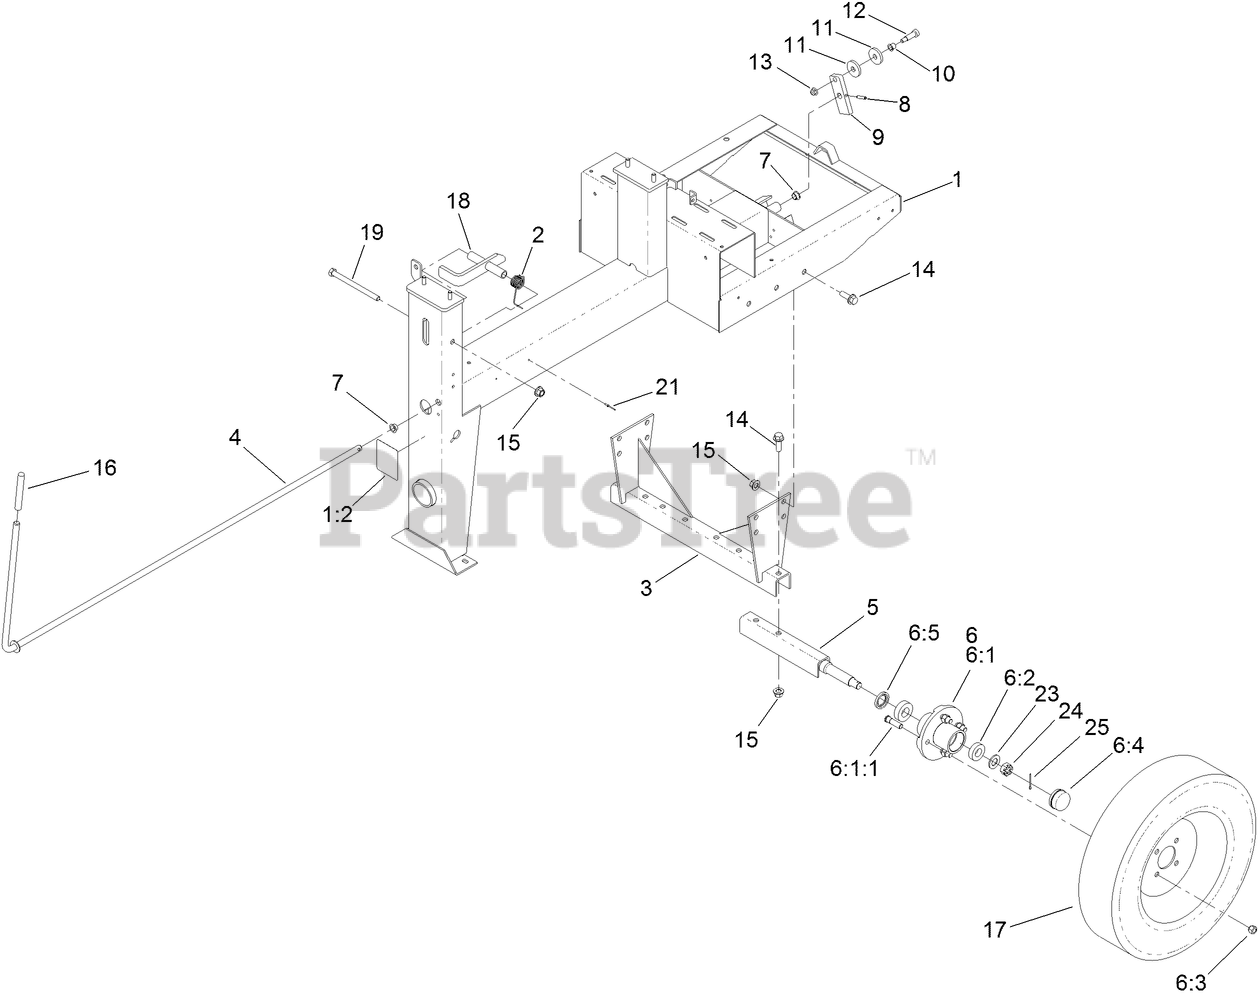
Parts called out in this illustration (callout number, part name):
1	FRAME ASM
1:2	DECAL-SAFETY CHAIN, TOWING
2	SPRING-TORSION
3	SUPPORT-AXLE
4	LEVER-CLUTCH
5	AXLE-HALF
6	HUB ASM
6:1	HUB-4IN
6:1:1	STUD-WHEEL
6:2	BEARING-ROLLER
6:3	NUT-LUG
6:4	CAP-DUST
6:5	SEAL-HUB, WHEEL
7	BUSHING-FLANGE
8	PIN-SPRING
9	LINK-CLUTCH
10	BUSHING-FLANGE
11	WASHER-FLAT
12	SCREW-HSBH
13	NUT-HF, NI
14	SCREW-HHF
15	NUT-LOCK
16	GRIP-HANDLE
17	TIRE AND RIM ASM
18	LATCH-DRUM
19	SCREW-HH
21	RIVET
23	WASHER-FLAT
25	PIN-COTTER
